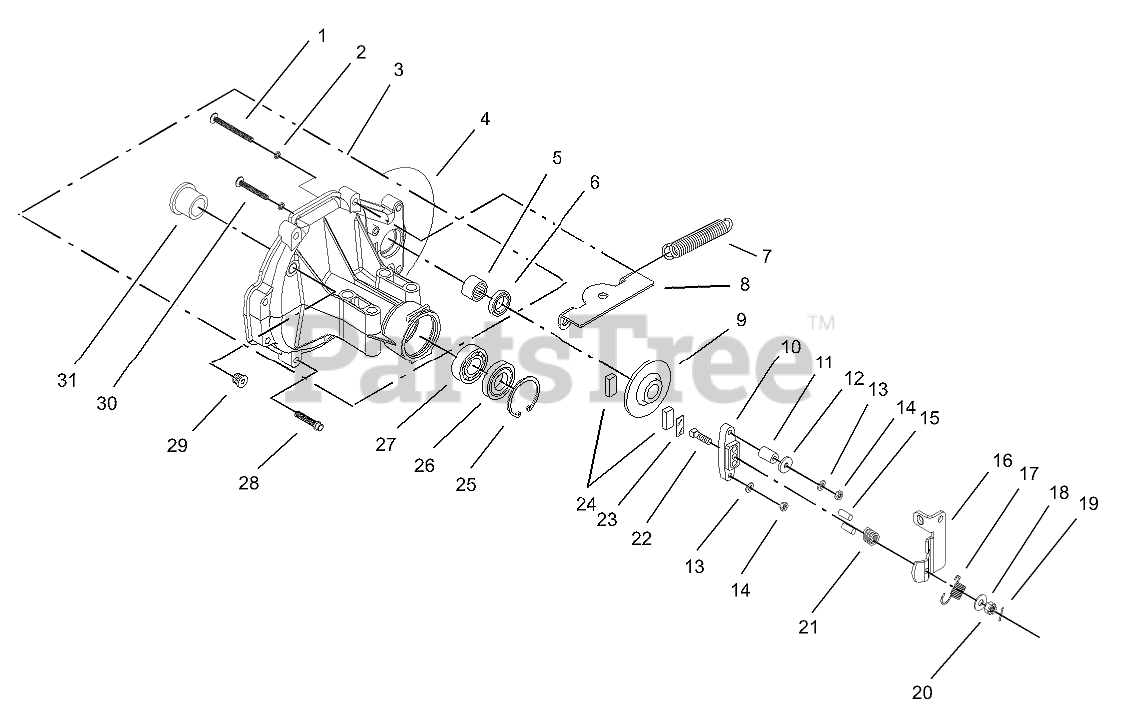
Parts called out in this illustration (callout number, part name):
2	O-RING
3	RH HOUSING ASM
4	SEALANT
5	BEARING-NEEDLE
6	SEAL-LIP
7	SPRING-RETURN
8	BRACKET-CRANK, BELL
9	DISK-BRAKE
10	YOKE-BRAKE
11	SPACER
12	WASHER
13	WASHER-LOCK
15	PIN-BRAKE
16	ARM-BRAKE
17	SPRING-ARM, BRAKE (BIAS)
18	WASHER
19	PIN-COTTER
20	NUT-CASTLE
21	SPRING-BRAKE, ANTI DRAG
22	BOLT-SQH
23	PUCK-PLATE
24	PUCK-BRAKE
25	RING-RETAINING
27	BEARING-BALL
28	SCREW-TTH
29	PLUG-THREAD, STRAIGHT
31	BEARING-FLANGE
